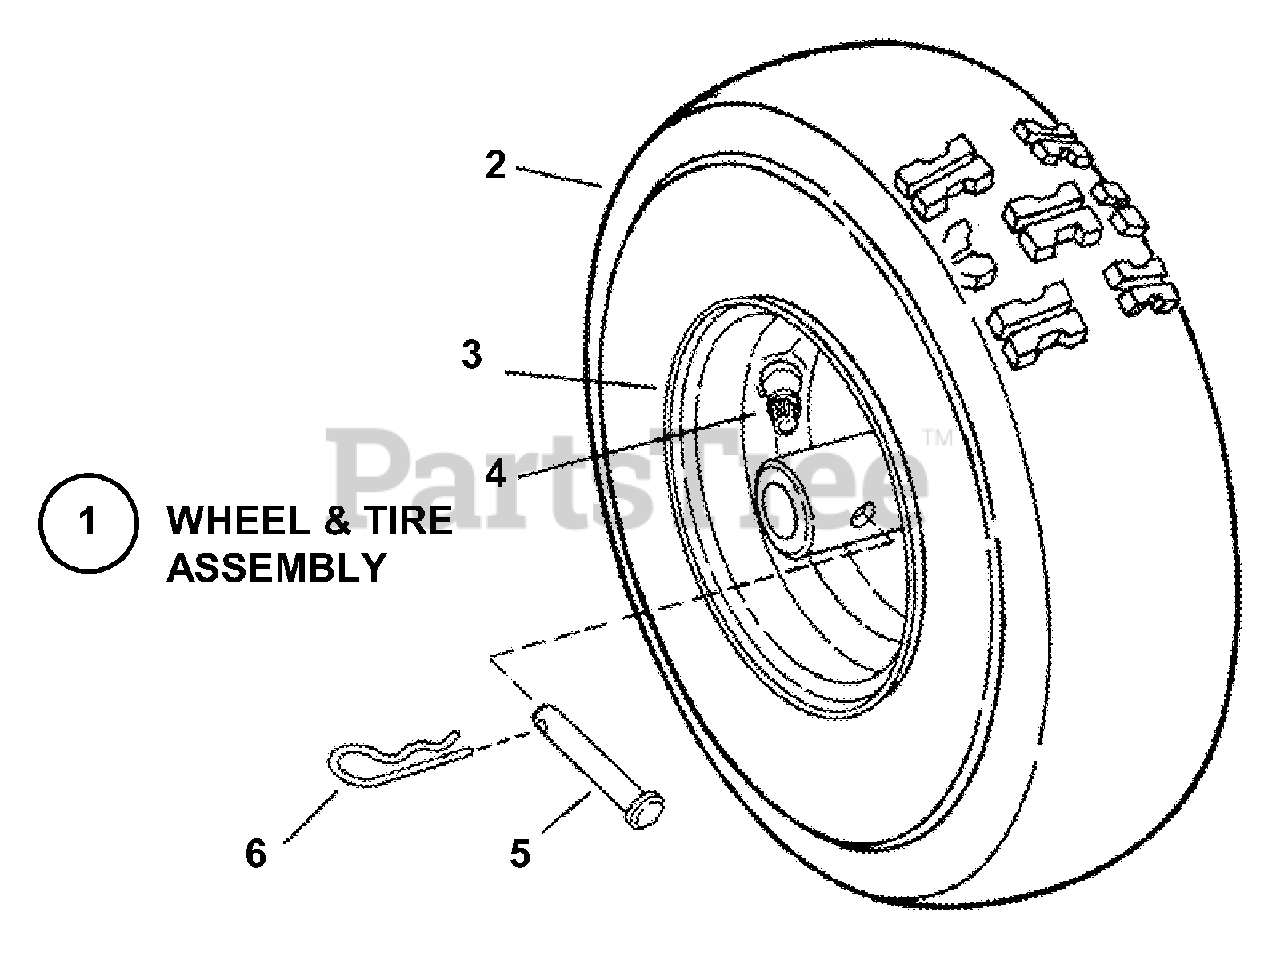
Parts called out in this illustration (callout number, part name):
1	TIRE & RIM ASSY, 13x4.10/3.50-6 (Snow Hog)
1	TIRE & RIM ASSY, 13x4.50/5.00-6 (Snow Hog)
2	TIRE, 13x4.10/3.50-6
2	TIRE, 13x4.50/5.00-6
3	RIM, 6 x 3.25
4	VALVE, Snap-In
5	PIN, 5/16 x 1-11/16" Clevis
6	PIN, 3/32 x 1-1/2" Hair
